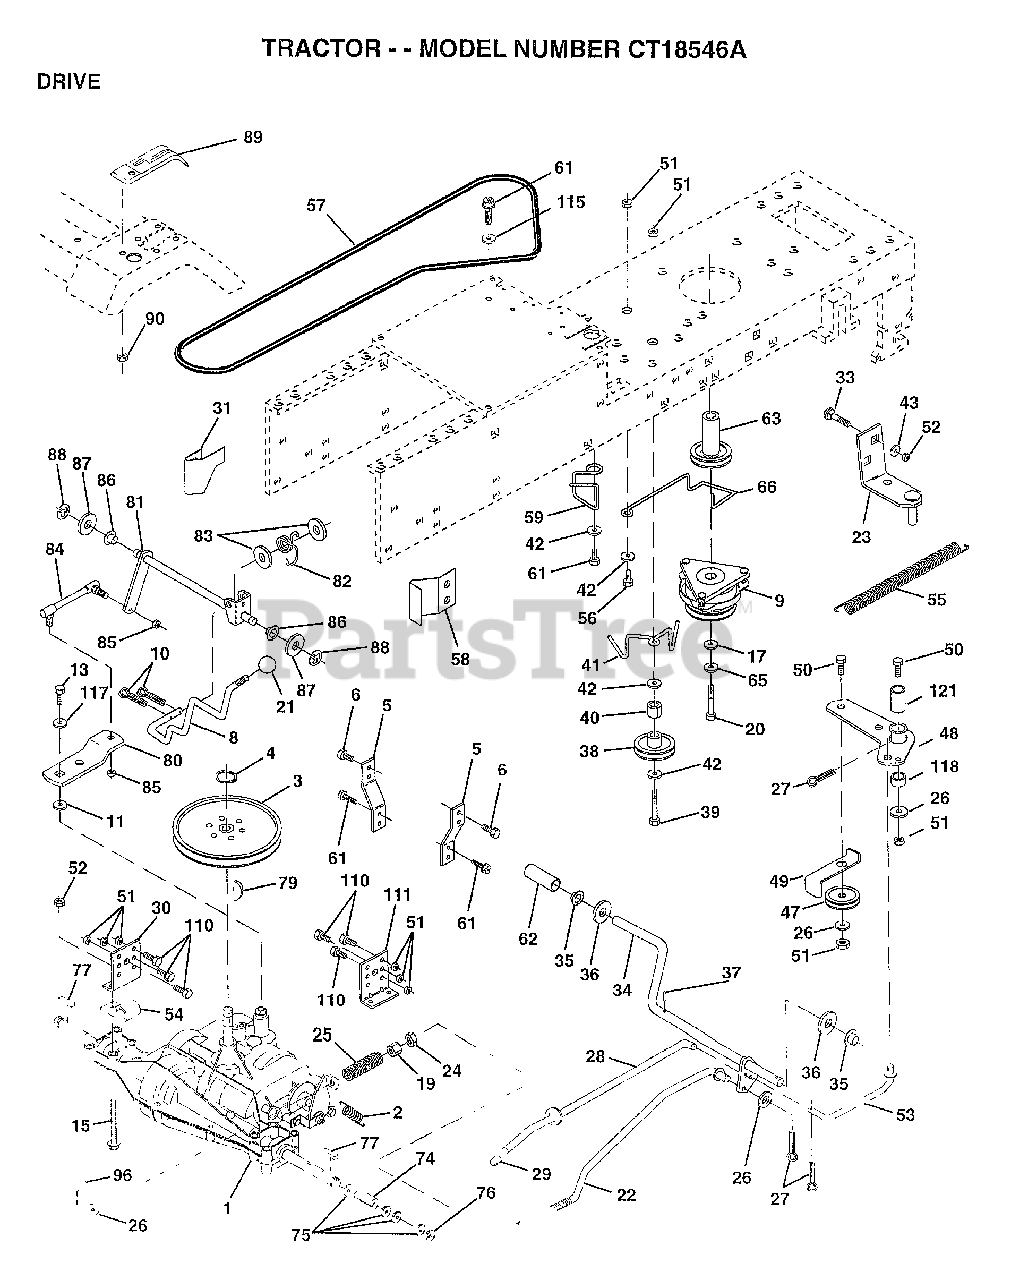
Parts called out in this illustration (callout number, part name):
3	PULLEY TRANSAXLE
4	RING
5	STRAP TORQUE
6	SCREW
8	ROD SHIFT FEND YT
10	PIN COTTER 1/8
11	WASH-SHFT PLT LT
13	BOLT.1/4-28.W/PAT
15	BOLT.HX.FLG.5/16
17	WASHER
19	NUT
20	BOLT.7/16-20X4.25
21	KNOB T (1/2-HOLE)
22	ROD.ASM.BK.44.MWR
23	BRACKET.ASM.MTG
24	NUT
25	"SPRING,ROD BRAKE"
26	WASHER
27	COTTER PIN
28	ROD.BRAKE.PARK.LT
29	PLUNGER CAP T
30	BRKT TRANS LH
31	KEEPER BELT LH
33	BOLT
34	SHAFT ASM-PEDAL F
35	NYLON BEARING
36	WASHER LT
38	PULLEY.IDLER.FLAT
39	BOLT
40	SPACER T
41	KEEPER, IDLER
42	WASHER
43	WASHER T
48	BELLCRANK ASM
49	RETAIN BELT
53	"LINK, CLUTCH T"
54	"CLIP,INSULATOR"
55	"SPRING, RETURN LT"
57	BELT.GRDRV.94.75
58	"KEEPER,BELT RH"
59	KEEPER BELT CNTSP
61	SCREW
62	PEDAL COVER T
63	PULLEY ENGINE
65	LOCKWASHER
66	KEEPER-BELT
74	SPACER HYT
75	WASHER
76	E RING HYT
77	SQ KEY STD
80	"ARM,SHIFT"
81	"SHAFT,SHIFTER"
82	"SPRING,TORSION"
83	WASHER
84	"ROD LINK,SHIFT AD"
85	NUT.CNT.LOCK.1/4
86	BUSHING
87	WASHER D
88	KLIP RING
89	CONSOLE SHIFTER
90	NUT
96	RETAINER M
111	BRKT TRANS RH
115	WASHER GT
117	WASHER PM
118	SPACER-BELLCRANK
121	NYLINER-CLUTCHING
